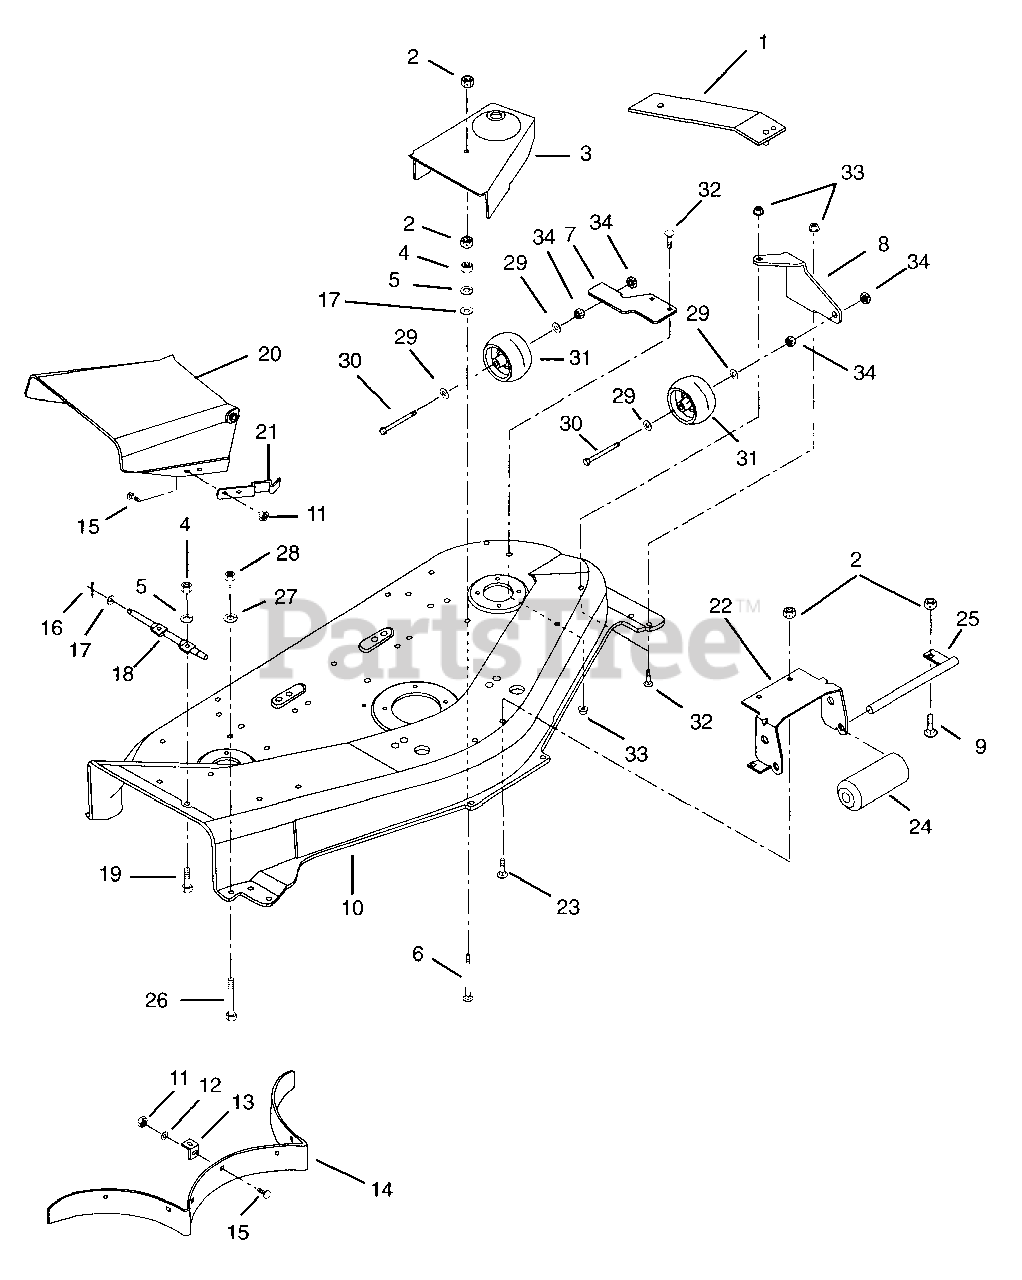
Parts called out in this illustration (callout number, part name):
2	@NUT-LK-CTR .31-18 YWZC
3	COVER R.H. BELT
3	L.H. BELT GUARD
4	@NUT-HEX .31-18 YWZC
5	WSHR-LK .312X.097 HVY YWZC
6	BLT-RDHDSQNK .31-18X3.25 SHTPL
7	BRACKET - LEFT REAR
8	BRACKET - LEFT FRONT
9	@BLT-RDHDSQNK .31-18X.75 G5YZ
10	MOWER PAN W/DECALS 48"- ORANGE
11	@NUT-LK-CTR .25-20 YWZC
12	@WSHR-FL-STL.281X.62X.065 YWZC
13	BAFFLE TAB
15	BLT-RDHDSQSHNK.25-20X.50 YWZC
16	@PIN-CTR .09X.75 EXTPRSQCT YWZ
17	@WSHR-FL-STL.406X.812X.065 YWZ
18	HINGE PIN
19	@BLT-HEX .31-18X.75 GR5 YWZC
20	CHUTE EXTENSION
21	SPRING, FLAT
22	BRACKET, ROLLER
23	@BLT-RHDSSQNK .31-18X.62 G5YZ
25	ROLLER SHAFT
26	@BLT-HEX .38-16X2.50 GR5 YWZC
27	WSHR-LK .375X.130 YWZC
28	@NUT-HEX .38-16 YWZC
29	WSHR-FL-NYL .518X1.000X.080
30	@BLT-HEX .50-13X4.50 GR5 YWZC
31	WHEEL 5 X 3
32	BLT-RDHDSQSHK.31-18X.75 GR2 YW
33	@NUT-SPNLK-FLG .312-18 YWZC
34	@NUT-LK-CTR .50-13 YWZC
